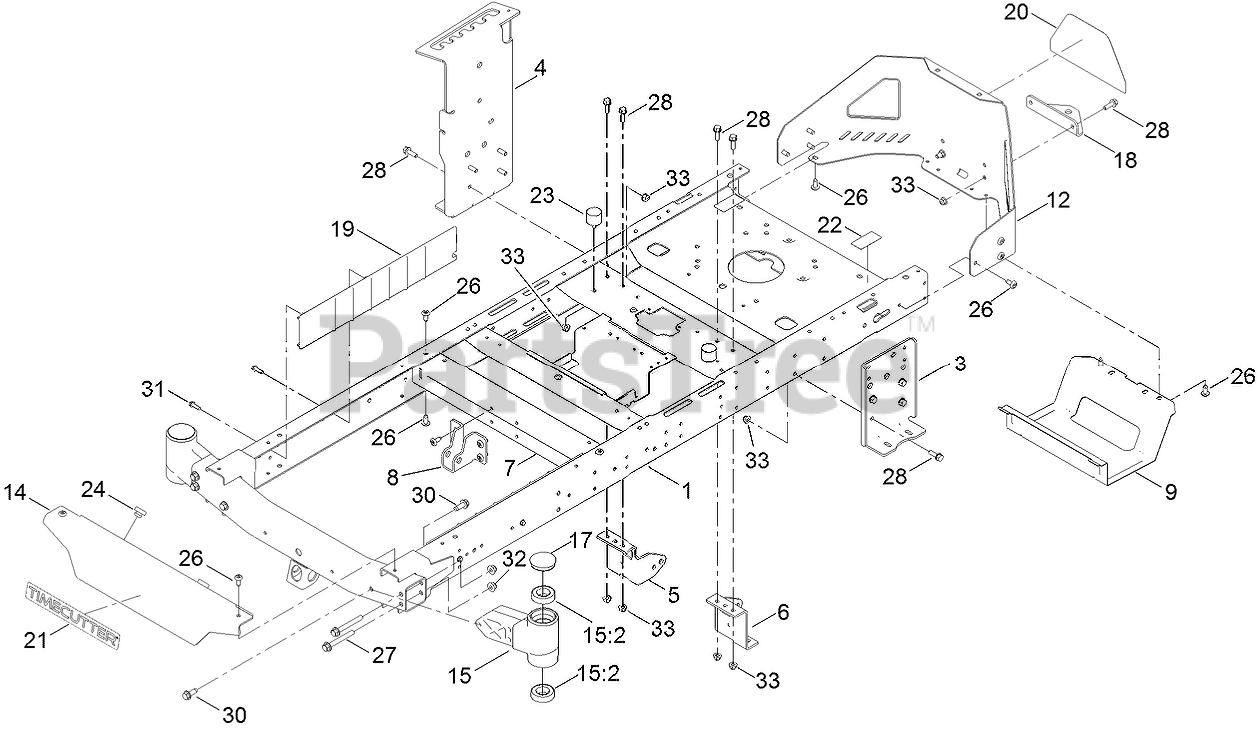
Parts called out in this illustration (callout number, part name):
1	FRAME ASSEMBLY
3	PLATE-MOUNT, HYDRO
4	PLATE-MOUNT HYDRO, RH
5	MOUNT-HYDRO, FRONT (RIGHT)
6	MOUNT-HYDRO, FRONT (LEFT)
7	BRACE-CROSS, LOWER
8	BRACKET-MOUNT DAMPER, LOWER
9	GUARD-MUFFLER
12	GUARD-ENGINE
14	FOOTREST
15	AXLE STUB ASM
15:2	BEARING-BALL
17	CAP-GREASE
18	BRACKET-HITCH
19	GUARD-RAIL
20	DECAL-TIMECUTTER
21	DECAL-TIMECUTTER
22	DECAL-BYPASS
23	BUMPER-RUBBER
24	BUMPER-RUBBER
27	SCREW-HHF
28	SCREW-HHF
30	SCREW-HWH
31	SCREW-HWH
32	NUT-HF, NI
33	NUT-HF, NI
